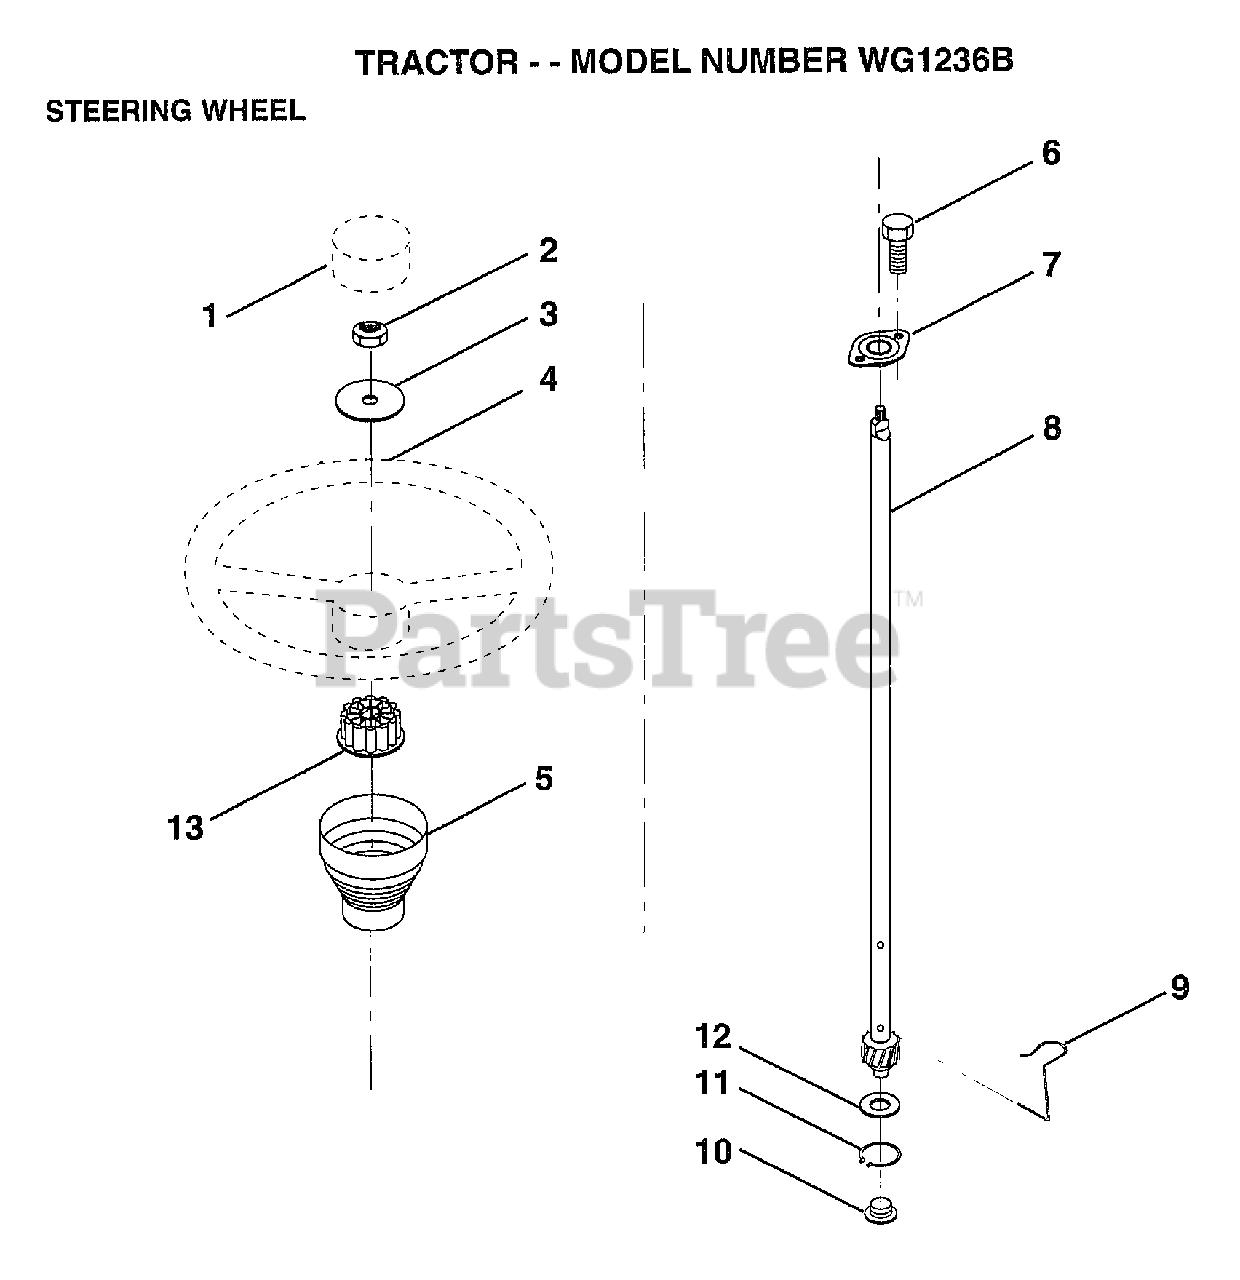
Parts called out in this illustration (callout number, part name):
1	ST WHL INSERT CAP
2	GRIPCO NUT
3	WASHER T
5	SLEEVE STEERING
9	STEERING CLIP
10	BUSHING STEER LWR
11	RING
12	WASHER LT
13	ADAPTER-WHEEL LT
